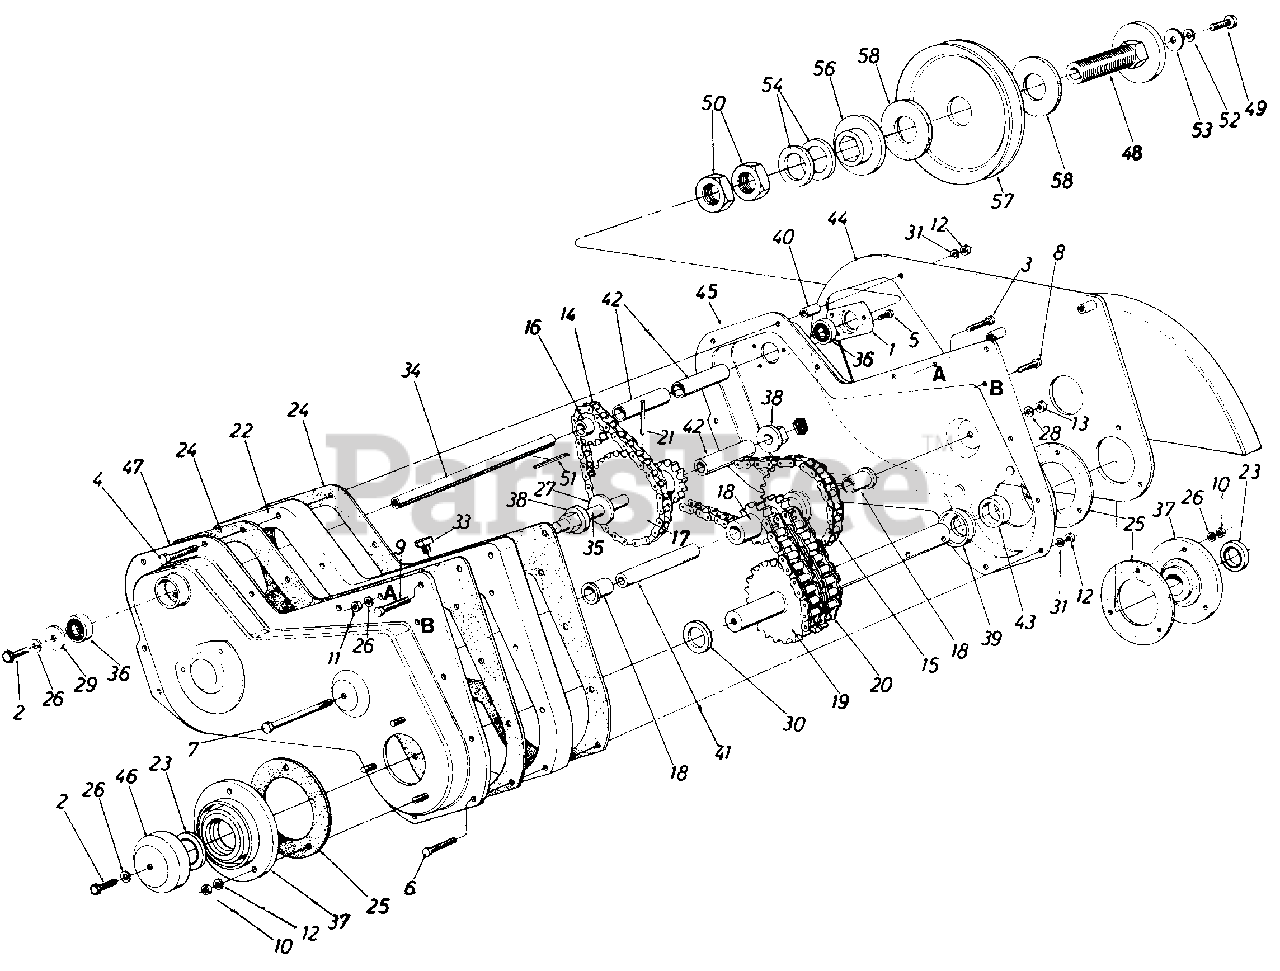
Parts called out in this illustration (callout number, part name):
1	Bearing Housing 1-3/8" Dia.
2	Hex Bolt 5/16-18 x .88" Lg. Spec.
3	Hex Bolt 5/16-18 x 1.50" Lg.*
4	Hex Bolt 1/4-20 x 2.75" Lg.*
5	Hex Wash. S-Tap. Scr. 1/4-20 x .50" Lg.
6	Hex Bolt 1/4-20 x 1.50" Lg.
7	Hex Bolt 3/8-16 x 4.5" Lg.
8	Hex Wash. Hd. Bolt 1/4-20 0 x 1.5" Lg.
9	Hex Wash. TT-Tap Scr. 5/16-18 x 1.75" Lg.
10	Hex Cent. L.-Nut 5/16-18 0 Thd.
11	Hex Nut 5/16-18 Thd.*
12	Hex Nut 1/4-20 Thd.*
13	Hex Nut 3/8-16 Thd.*
14	#41 Chain 1/2" Pitch x 34 0 Links-Endless
15	#42 Chain 1/2" Pitch x 48 0 Links-Endless
16	Sprocket 10 Tooth .500" Pitch
17	10 & 28 Teeth Sprocket Ass'y.
18	8-2 & 28 Sprocket Sleeve Ass'y.
19	18-2 Sprocket Shaft Ass'y.
20	#50-2 Chain 5/8" Pitch x 28 Links-Endless
21	Spring Pin Spir. 1/4" Dia. x 1.50" 4
22	Spacer Block-Tiller Housing
23	Oil Seal Double Lip-1-1/4" Dia.
24	Gasket for Tiller Housing
25	Gasket for Brg.-Housing
26	L.-Wash. 5/16" I.D.*
27	Fl.-Wash. .640" I.D. x 1.24" O.D.
28	L.-Wash. 3/8" I.D. Heavy Duty
29	Fl.-Wash. .344" I.D. x 1.125" O.D.
30	Special Washer
31	L.-Wash. 1/4" I.D.
33	Vent Plug
34	Jack Shaft .525" I.D. x 7.78" Lg.
35	Sprocket Shaft .63" Dia. x 5.0" Lg.
36	Ball Brg. .62" I.D. x 1.38" O.D.
37	Bearing Housing- 1-1/4"
38	Hex Flange Brg.
39	Spacer 1.25" I.D. x 2.0" O.D.
40	Spacer .28" I.D. x .62" O.D. x .90" Lg.
41	Spacer .38" I.D. x .62" O.D. x 3.44" Lg.
42	Spacer .62" I.D. x .88" O.D. x 1.56" Lg.
43	Spacer 1.25" I.D. x 1.62" O.D. x .50" 4.
46	Dust Cap .320" Dia. Hole
49	Hex Bolt 5/16-18 x 1.25" Lg. Grade 5
50	Hex Jam Nut 1.0-14 x 28 0 Thd.
51	Sq. Key 3/16 x 1.50" Lg.
52	L.-Wash. 5/16" I.D.*
53	Fl.-Wash. .344" I.D. x 1.125" O.D.
54	Spring Bell Wash. 1.0" I.D. x2.0" O.D.
56	Floating Disc 3-1/4" O.D. x 1.0" I.D.
57	5/8 V-Pulley 1.50" I.D. x 6.50"
58	Friction Pad 3-1/4" O.D. x 1-3/8" I.D.
